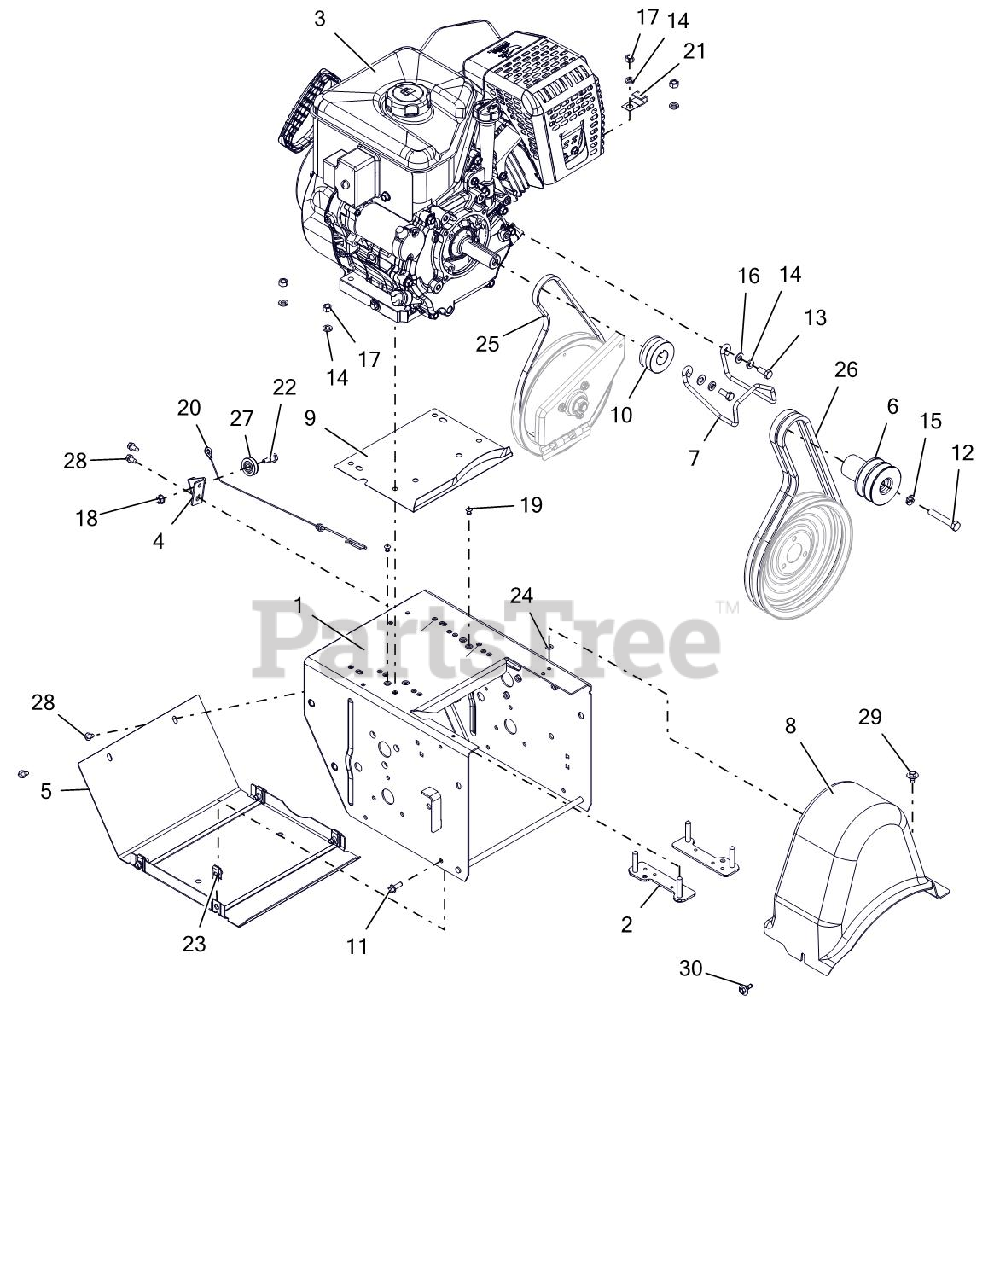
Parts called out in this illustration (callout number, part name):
1	FRAME, MAIN-DELUXE(WELDMENT)
2	STRAP, BOLT-LARGE
3	ENGINE,EFI369 GEN3 120V/60W
4	BRACKET, CABLE PULLEY
5	COVER, BOTTOM
6	SHEAVE, ATTACHMENT 2-GRV
7	FINGER, BELT
8	COVER, BELT-LARGE
9	BAFFLE, WATER - LARGE BLOCK
10	SHEAVE, DRIVE
11	BLT-HEX .25-20X.75 HWH YZ GR5
12	BLT-HEX .38-24X2.25 YWZC GR5
13	BLT-HEX .31-24X.75 YWZC GR5
14	WSHR-LK .312X.097 HVY YWZC
15	@WSHR-LK .38X.094 REG YWZC
16	@WSHR-FL-STL.344X.688X.065YWZC
17	@NUT-HEX .31-18 YWZC
18	@NUT-LK-TOP-FLG .25-20 YWZC
19	RVT-POP .187 YZ
20	CABLE, LOWER TRACTION,SS & PRO
21	J-CLAMP
22	BOLT, SHLDR-.375X.375X.25-20
23	NUT-RTNR .25-20X.56
24	NUT-PUSH .25X.50 O.D.
25	V-BELT, 3L-WRAPPED
26	V-BELT, HA-RAW EDGE (SET)
27	PULLEY, CABLE
28	SCR-TAP .25-20X.50 HWH TR YWZ
29	SCR-TAP .25-20X.50 LGHWH TR YZ
30	SCR-TAP .25-20X.5 CAPTIVE
